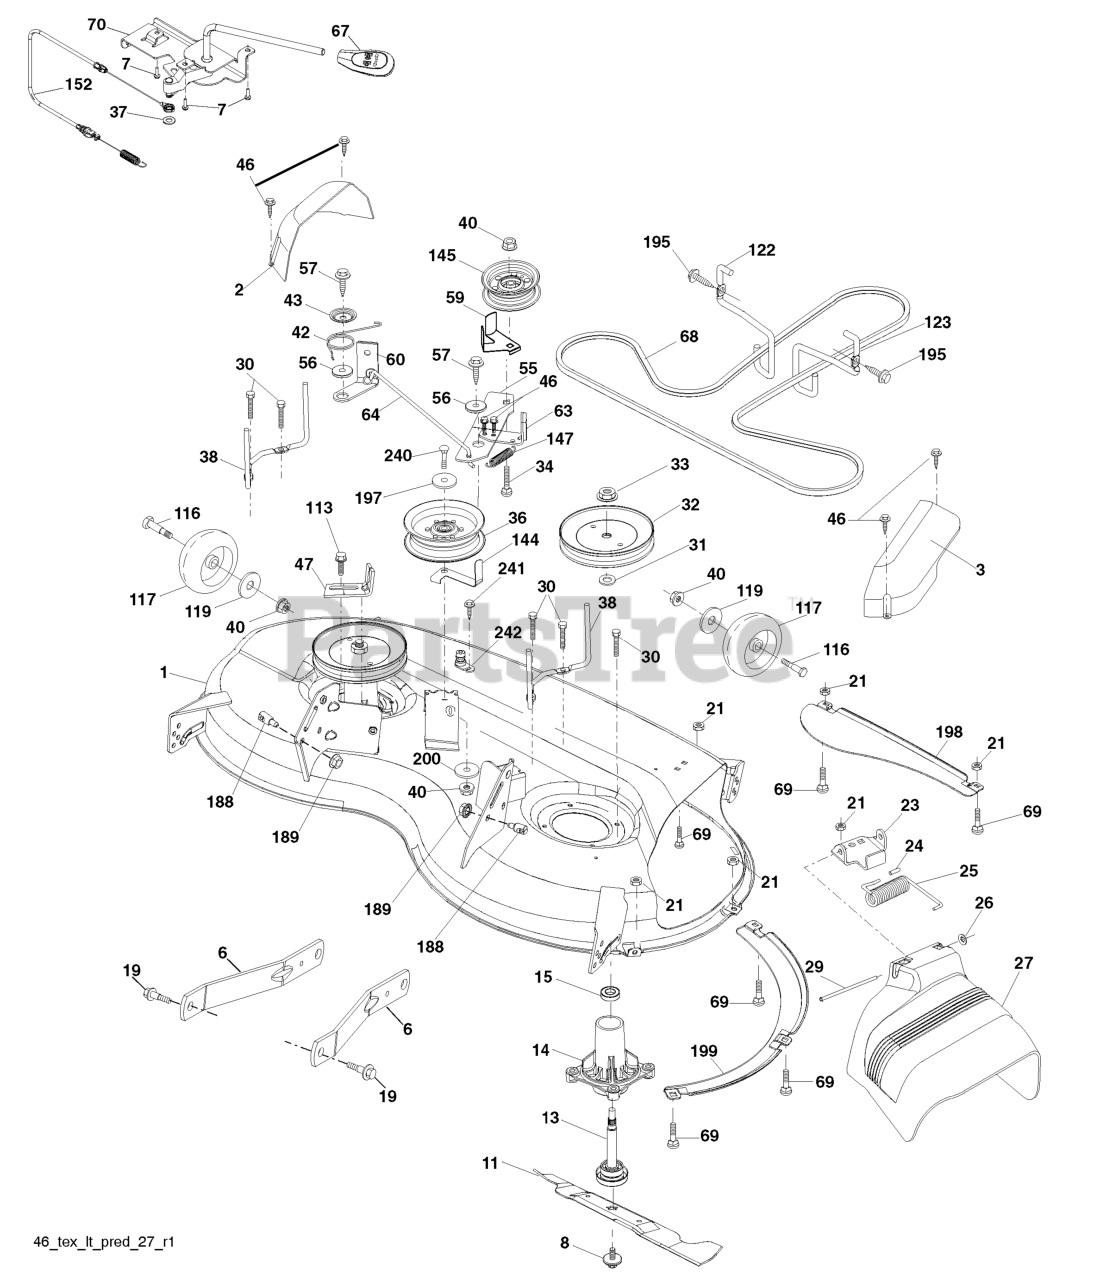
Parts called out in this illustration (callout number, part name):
1	DECK.WELDMENT.46"
2	COVER.MANDREL.RH.46"
3	COVER.MANDREL.LH.46"
6	ARM.SUSPENSION.MOWER.R
7	SCREW.#10 X 0.750.BOS
8	BOLT.WASHER.ASM.7/16-2
11	BLADE.MOWER.46".HI.LIFT
13	SHAFT.ASM.MDRL.N/GREASE.38
14	RP.HOUSING.MANDREL.4PT.
19	BOLT.SHOULDER
21	LOCKNUT
23	BRKT.DEFLECTOR.38"2005+
24	CAP-SLEEVE LT
25	SPRING.TORSION.DEFLECT
26	NUT PUSH M
27	SHIELD.DEFLECTOR.MOWER.46"BLAC
29	ROD.HINGE
30	SCREW, WASHER HEAD
31	WASHER.SPACER.MANDREL
32	PULLEY.MANDREL.5.438.PD
33	NUT.FLANGE.LOCK.TOP
34	BOLT.3/8-16X1.50
36	PULLEY.IDLER.2006
37	WASHER
38	KEEPER.BELT.MANDREL.PULLEY
40	NUT LOCK FLG 3/8-16 UNC
42	SPRING.TORSION.BRAKE
43	SRPING.TORSION.RETAINE
46	SCREW.1/4-20X5/8
47	BRKT.CLUTCH.CABLE
55	IDLER.ARM
56	SPACER.RETAINER
57	SCREW 3/8-16X1
59	GUARD, BELT
60	ARM BRAKE MOWER RH 38"
63	ARM BRAKE MOWER
64	LINKAGE BRAKE
67	HANDLE.CLUTCH.CABLE.LT
68	V-BELT
69	BOLT
70	CLUTCH.ASM.CABLE.HUSQ.TEX
113	BOLT.5/16HEX.WHS.HD
116	BOLT.SHOULDER.3/8-16X3-5/8.
117	RP WHEEL. GUAGE RALLY
119	WASHER
122	KEEPER BELT ENGINE LH
123	KEEPER BELT RH
144	KEEPER.BELT.MOWER
145	PULLEY.IDLER.48"PRIMARY
147	SPRING RETURN
152	CABLE CLUTCH MANUAL W/SPR.
188	STUD.FASTNER.W/ANTI-ROTATE
189	NUT LOCK HEX FLANGE 5/16-18
195	SCREW, 3/8-16X3/4
197	WASHER
198	BAFFLE CENTER FRONT
199	BAFFLE FRONT RH
200	WASHER.13/32 X 1 X 1/2.11GUARD
240	BOLT-HEX EAK
241	SCREW.TT.#10-32X.5.3/8.FLANGE
242	PORT.WASHOUT
